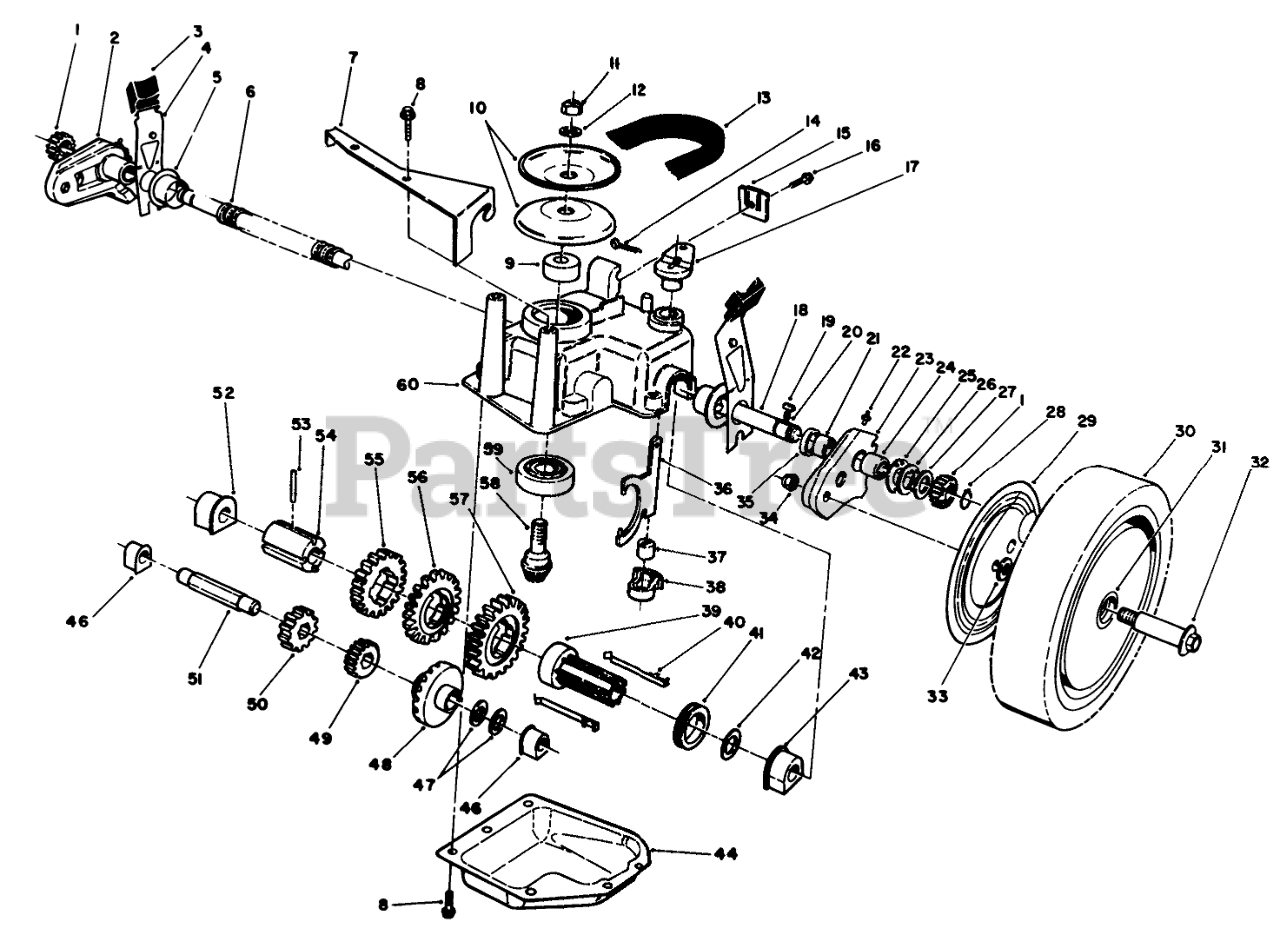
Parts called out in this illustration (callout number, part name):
1	GEAR-PINION
2	Pivot Arm Assembly-R.H. (Incl. Ref. #21, 22, 24 & 35)
3	KNOB-ARM
4	SPRING ARM ASM SP
5	CAP-END
6	CONDUIT-CONVOLUTED, SPLIT
7	Bracket-Guide
8	SCREW-HWHTF
9	SPACER
10	Pulley Half
11	NUT-HEX
12	WASHER-FLAT
13	V-BELT E
14	PIN-COTTER
15	Cable Clamp
16	SCREW-HWHTF
17	SHIFT LEVER
18	Output Shaft
19	KEY RECTANGULAR
20	SPRING-COMPRESSION
21	BUSHING
22	FITTING-GREASE
23	Pivot Arm Assembly-L.H. (Incl. Ref. #21, 22, 24 & 35)
24	BEARING-ROLLER
25	INNER THRUST WASHER
26	WASHER-THRUST, OUTER
27	WASHER-THRUST, OUTER
28	PIN-ROLL
29	WHEEL COVER
30	Wheel-Tire & Gear Assy. (Incl. Ref. #31)
31	BUSHING
32	WHEEL BOLT
33	WASHER
34	Nut
35	SEAL-OIL
36	YOKE-SHIFT
37	BUSHING-YOKE
38	RETAINER-FORK, SHIFT
39	Sleeve-Shift Key
40	Key Shift
41	SHIFT COLLAR
42	WASHER-PLAIN
43	BUSHING-OUTPUT
44	Cover-Gearcase
46	BUSHING
47	WASHER-THRUST
48	Gear-Bevel
49	PINION-20T
50	PINION-25T
51	SHAFT-INTERMEDIATE
52	BUSHING
53	PIN-SPRING
54	SLEEVE-GEAR
55	GEAR-39T
56	GEAR-44T
57	GEAR-49T
58	Gear-Pinion
59	BEARING-BALL
60	CASE-GEAR, UPPER
